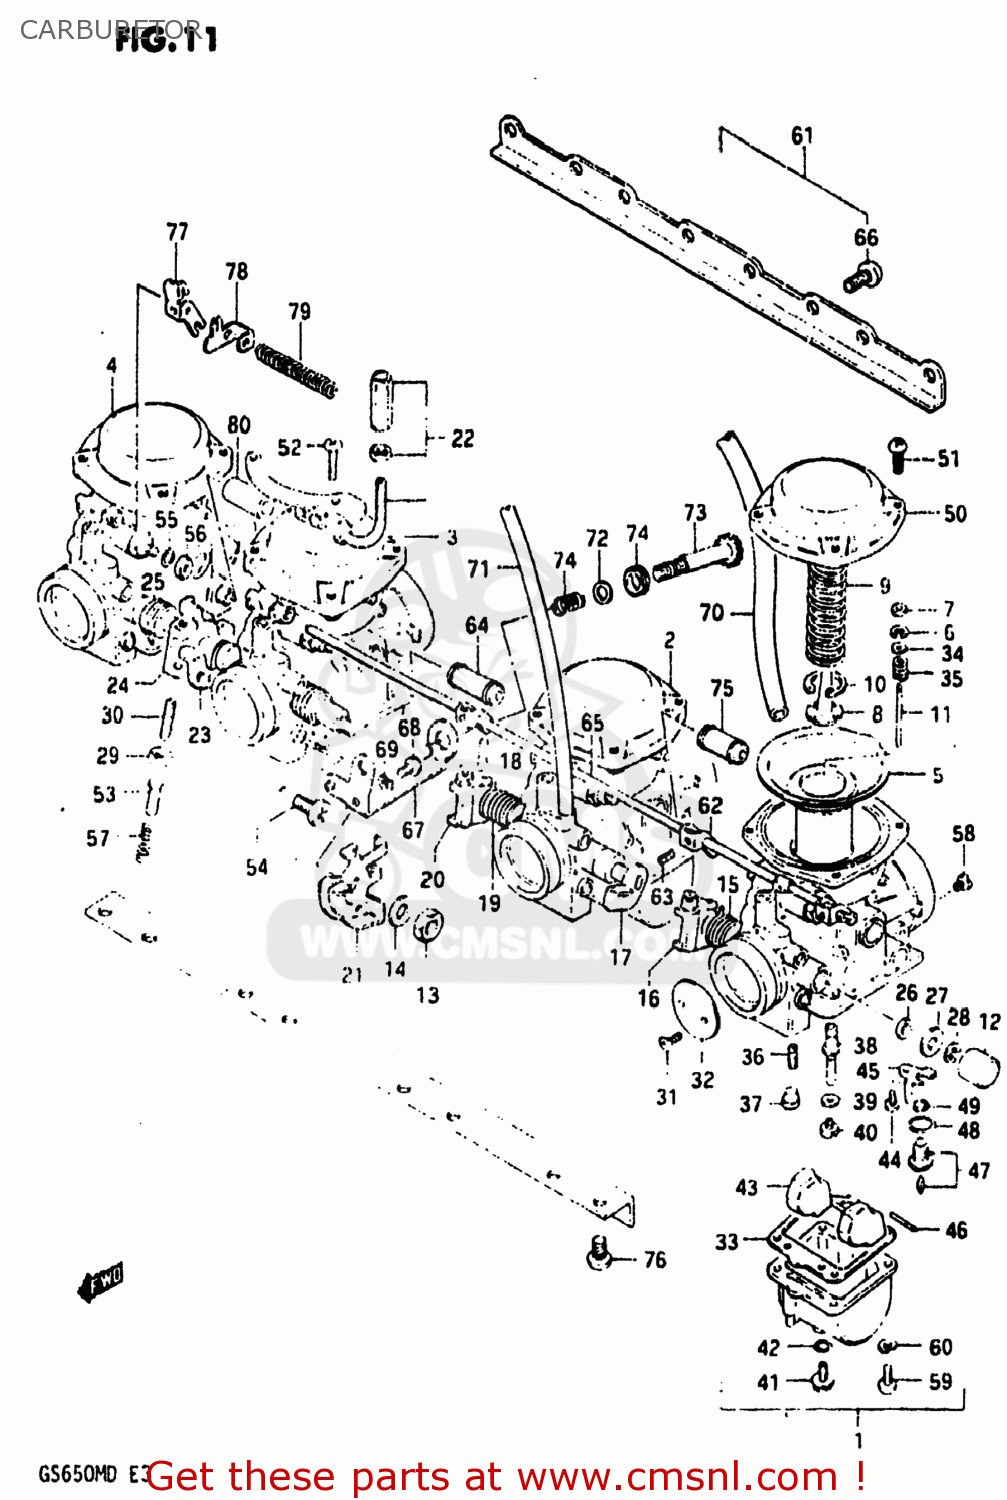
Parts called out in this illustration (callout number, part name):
1	CARBURETOR ASSEMBLY
2	CARBURETOR ASSEMBLY
3	CARBURETOR ASSEMBLY
4	CARBURETOR ASSEMBLY
5	DIAPHRAGM ASSEMBLY
6	CLIP,NEEDLE
7	RING
8	HOLDER,GUIDE
9	SPRING
10	E RING
11	NEEDLE JET
12	CAP
13	NUT 8MM
14	WASHER
15	SPRING,THROTTLE SHAFT
16	SHAFT,THROTTLE
17	SHAFT,THROTTLE
18	PIN,THROTTLE SHAFT
19	SPRING,THROTTLE SHAFT
20	LEVER,THROTTLE SHAFT
21	LEVER ASSEMBLY,THROTTLE
22	BRACKET
23	SHAFT,THROTTLE
24	SHAFT,THROTTLE
25	SPRING,THROTTLE SHAFT
26	SEAL
27	GASKET,THROTTLE SHAFT (NAS)
28	E RING
29	NUT
30	SCREW
31	SCREW
32	VALVE,THROTTLE (BUTTERFLY)
33	GASKET,FLOAT CHAMBER (NAS)
34	WASHER
35	SPRING
36	JET,PILOT(42.5)
37	PLUG,NEEDLE JET
38	JET,NEEDLE
39	WASHER,NEEDLE NOZZLE
40	JET,MAIN(110)
41	PLUG,DRAIN
42	GASKET (NAS)
43	FLOAT
44	SCREW 4X6
45	PLATE,NEEDLE VALVE FITING
46	PIN,FLOAT
47	VALVE ASSEMBLY,NEEDLE
48	O-RING,NEEDLE VALVE
49	FILTER
50	COVER
51	SCREW
52	SCREW
53	PIN,THROTTLE LEVER
54	SCREW
55	O RING
56	CAP,STARTER VALVE
57	SPRING,THROTTLE SCREW
58	JET
59	SCREW
60	LOCK WASHER
61	CARBURETOR ASSEMBLY
62	LEVER
63	SCREW
64	PIPE
65	SHAFT,STARTER
66	SCREW
67	BRACKET,THROTTLE ADJUST
68	SCREW
69	WASHER,LOCK
70	HOSE
71	HOSE
72	WASHER
73	ADJUSTER
74	BUSH
75	PIPE
76	SCREW
77	LEVER
78	LEVER
79	SPRING,CHOKE CABLE
80	HOSE
